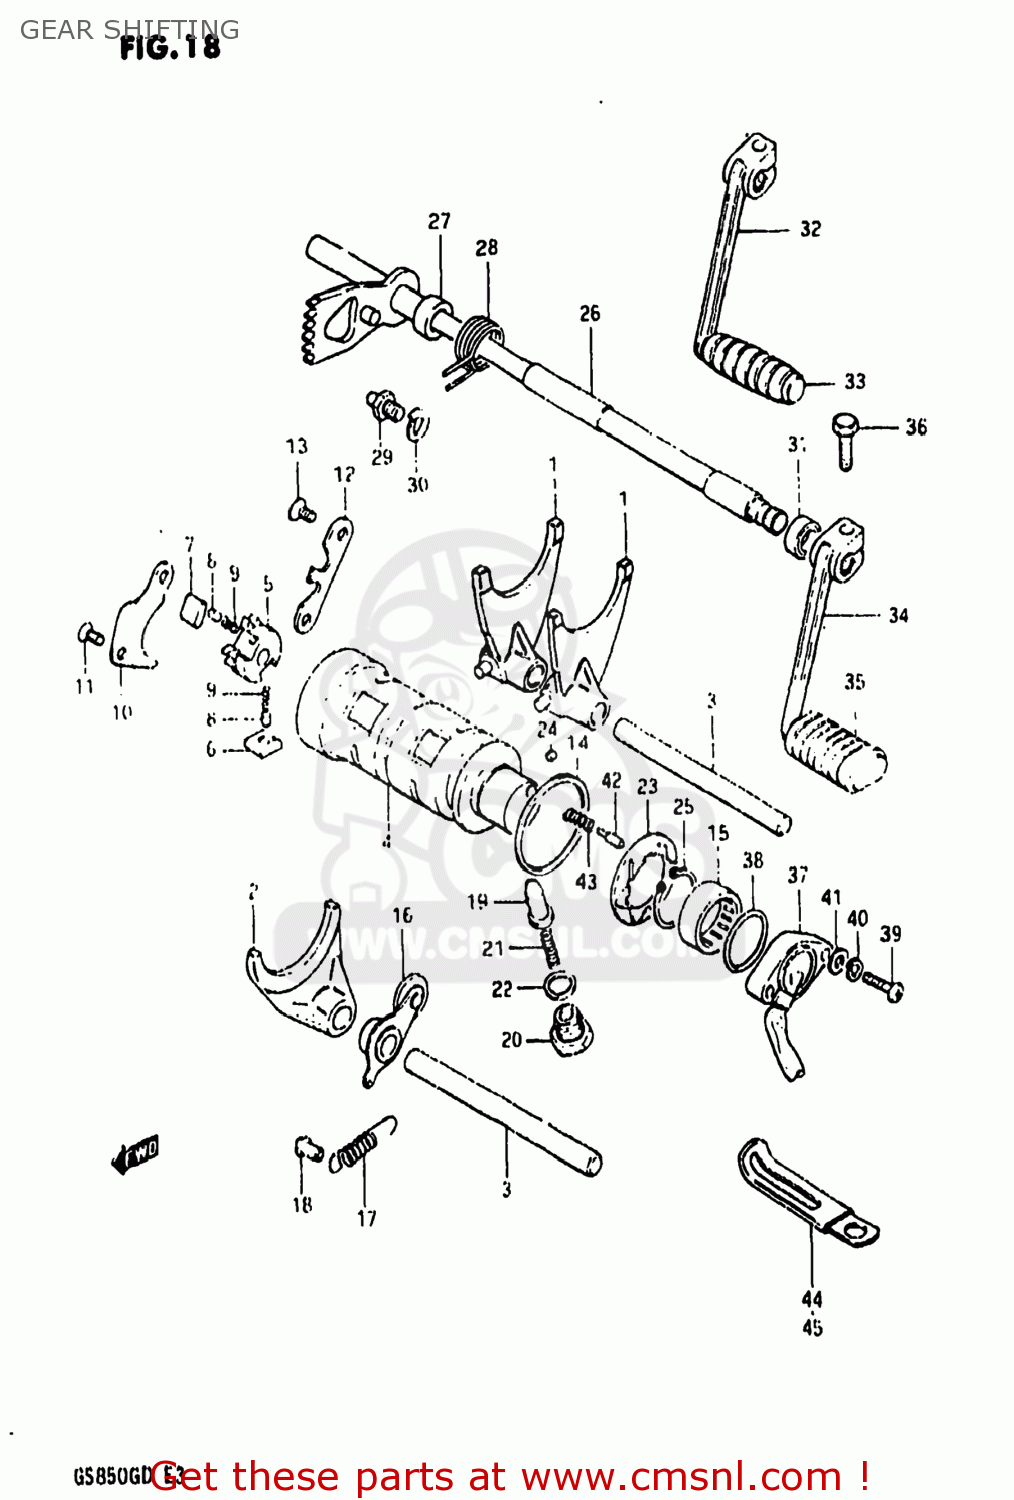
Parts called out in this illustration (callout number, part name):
1	FORK,GEAR SHIFT NO.1
2	FORK,GEAR SHIFT NO.3
3	SHAFT,GEAR SHIFT FORK
4	CAM,GEAR SHIFT
5	RETAINER,GEAR SHIFT CAM
6	PAWL,GEAR SHIFT NO.1
7	PAWL,GEAR SHIFT NO.2
8	PIN(5X8)
9	SPRING
10	LIFTER,GEAR SHIFT PAWL
11	SCREW
12	GUIDE,GEAR SHIFT CAM
13	SCREW
14	WASHER(40X45X1)
15	BEARING(25X32X12)
16	STOPPER,GEAR SHIFTING
17	SPRING
18	RIVET
19	STOPPER,GEAR SHIFT CAM NO.2
20	HOLDER,GEAR SHIFT CAM STOP SPR
21	SPRING
22	GASKET(14X19.2X2) (NAS)
23	PLATE,GEAR SHIFT CAM STOPPER
24	PIN 4X6
25	CIRCLIP,25MM
26	SHAFT,GEAR SHIFT
27	SPACER (12X20X12)
28	SPRING
29	STOPPER,GEAR SHIFT CAM
30	WASHER
31	OIL SEAL
32	LEVER ASSEMBLY,GEAR SHIFTING
33	RUBBER,GEAR SHIFT PEDAL
34	LEVER ASSEMBLY,GEAR SHIFTING
35	RUBBER,PEDAL
36	BOLT
37	TERMINAL BASE ASSY,GEAR SHIFT
38	O-RING (D:2.4 ID:26.2)
39	SCREW 5X20
40	LOCK WASHER
41	WASHER
42	PIN(5X15.5)
43	SPRING
44	CLAMP L:35
45	CLAMP
